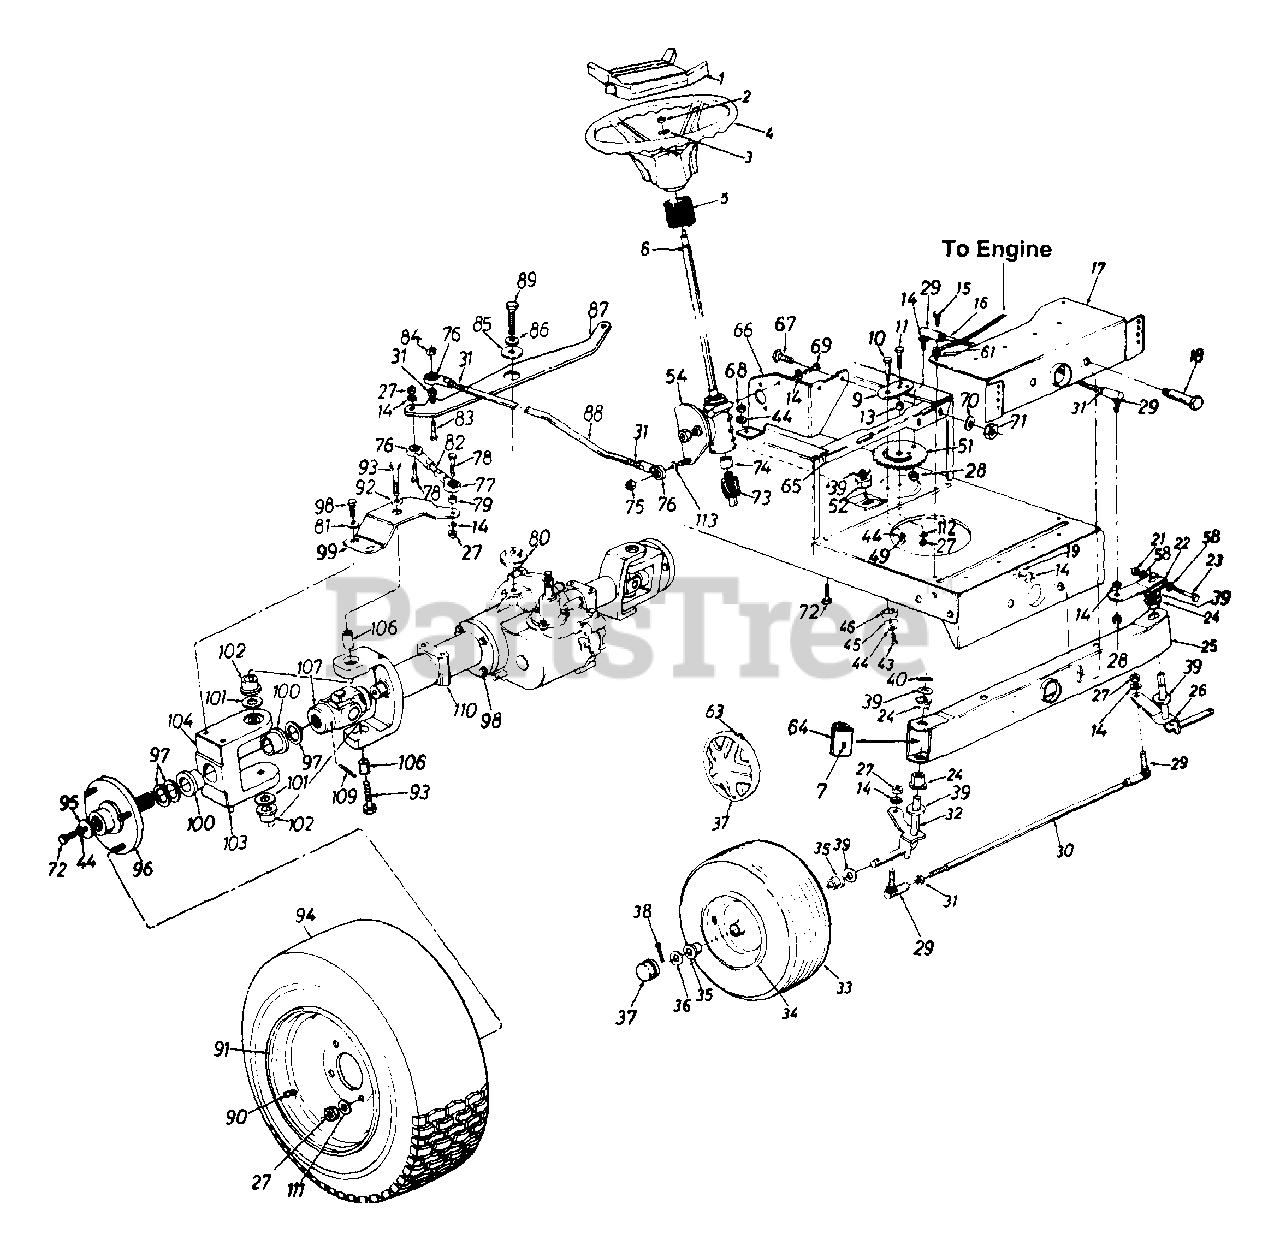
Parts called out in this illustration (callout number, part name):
1	Steering Wheel Insert
2	Hex L-Nut 5/16-24 Thd.
3	Belleville Wash..345" I.D.
4	Steering Wheel (4 Spoke)
5	Steering Bellow
6	Steering Shaft Ass'y.
7	Grease Fittings
9	Retainer Plate
10	Shoulder Bolt .437" Dia. x .35" Lg. 5/16-18 Thd.
11	Hex Bolt 3/8-24 x 1.0" Lg. (Grade 5)
13	Spacer.380" I D. x.625" O.D. x .227"
14	L-Wash. 3/8" I.D.
15	Hex Wash. Hd. Self-Tap Scr.
16	Steering Drag Link
17	Front Pivot Brkt.
18	Shoulder Bolt .498" Dia. x 2.04" Lg. 3/8-16 Thd.
19	Hex Nut 3/8-16 Thd.
21	Hex Cent. L-Nut 5/16-24 Thd.
22	Steering Arm Front Axle
23	Hex Bolt 5/16-24 x 2.00" Lg. (Grade 5)
24	Hex Flg. Brg..634" I.D.
26	Front Axle Ass'y.- L.H.
27	Hex Nut 3/8-24 Thd.
28	Hex Jam Nut 3/8-24 Thd.
29	Ball Joint 3/8-24 Thd.
30	Tie Rod
31	Hex Jam Nut 3/8-24 Thd.
32	Front Axle Ass'y.- R.H.
35	Bearing 15" x 6" w/Plastic Bearing
36	Fl-Wash..635" I.D. x 1.59" O.D.
37	Front Hub Cap (Black)
38	Cotter Pin 1/8" Dia. x 1.25" Lg.
39	Fl-Wash..640" I.D. x .24" O.D.
40	Push Cap
43	Hex L-Bolt 5/16-18 x .62"
44	L-Wash. 5/16" I.D.
45	Fl-Wash..33" I.D. x 1.25" O.D.
46	Spacer (Plastic)
49	Hex Nut 5/16-18 Thd.
51	Steering Gear Segment
52	Hex Flg. Brg..634 I.D.
54	Steering Ass'y. Comp.
58	Wave Wash..32" I.D. x .62"
61	Ext. L-Wash. 5/16" I.D.
63	Spring Clip
64	Pivot Bar End Cap
65	Horizontal Cross Bracket
66	Vertical Mounting Bracket
67	Hex Bolt 1/4-28 x .75" Lg.
68	Hex Nut 5/16-24 Thd.
69	Hex Bolt 3/8-16 x 1.0" Lg.
70	Bell-Wash..265" 1.D. x .75"
71	Hex Nut 1/4-28 Thd.
72	Hex Bolt 5/16-24 x .75" Lg.
73	Pinion Shaft
74	Steering Shaft Splined Coupler
75	Hex L-Nut 3/8-24 Thd.
76	Rod End 3/8-24 Thd.- R.H.
77	Rod End 3/8-24 Thd.- L.H.
78	Hex Bolt 3/8-24 x 1.5" Lg. (Gr. 5)
79	Spacer.38" I.D. x .625"
80	Shld. Spacer .51" I.D.
81	Bell-Wash..38" I.D. x .88"
82	Tie Rod
83	Hex Bolt 3/8-24 x 1.25" Lg.
84	Hex Patch L-Nut 3/8-24 Thd.
85	Fl-Wash..531" I.D. x 1.75"
86	Bell-Wash..505" I.D. x 1.0"
89	Hex Bolt 1/2-13 x 1.5" Lg. (Gr. 5)
90	Air Valve
93	Hex Bolt 1/2-20 x 1.75" Lg. (Gr. 5)
95	Fl-Wash..33" I.D. x 1.25"
96	Wheel Flange Ass'y.
97	Fl-Wash. 1.0" x 1.56"
98	Hex Bolt 3/8-24 x 1.25" Lg.
101	Fl-Wash..76" I.D. x 1.5"
102	Flange Brg. 3/4" I.D.
103	Grease Fitting
104	Wheel Brg. Housing
106	Pivot Sleeve
107	U-Joint
109	Grooved Roll Pin 1.0" Lg.
110	Axle Horn Ass'y.
111	Bell-Wash..38" I.D. x .88"
112	Bell-Wash..39" I.D. x 1.38"
113	Fl-Wash..385" I.D. x .62"
